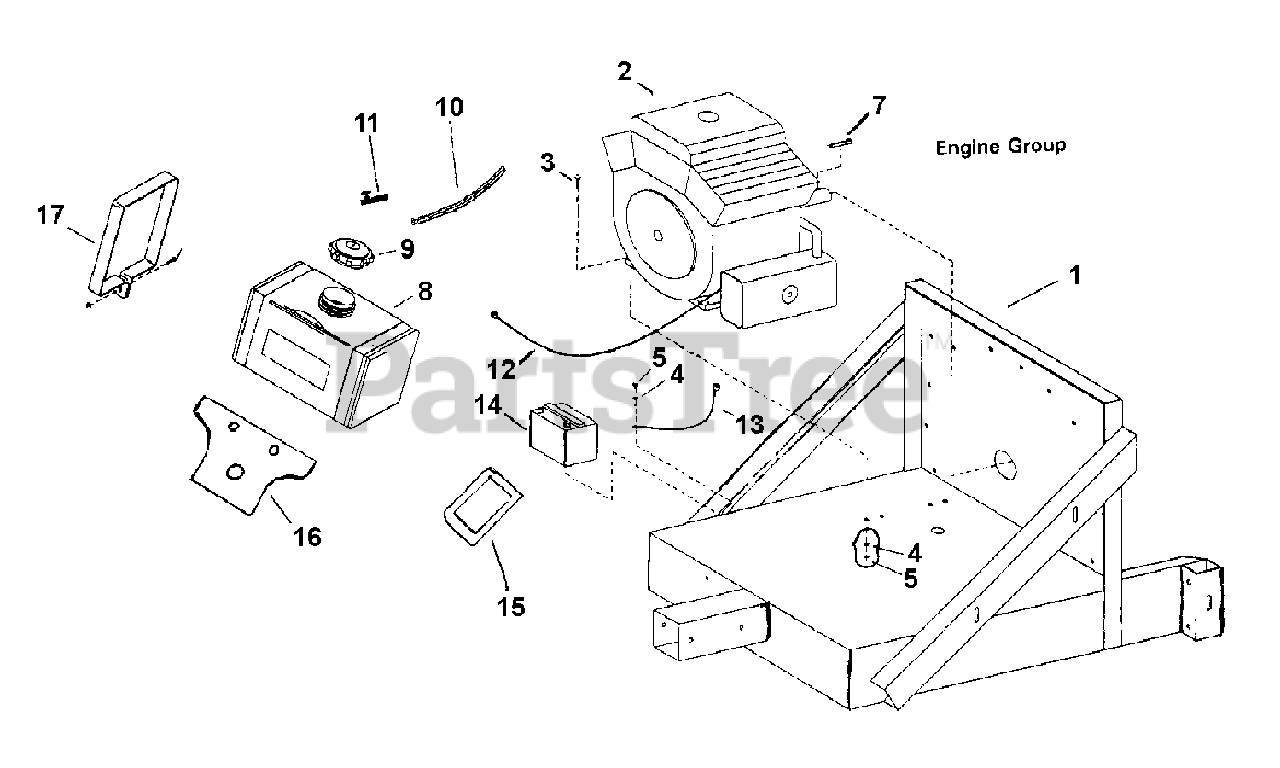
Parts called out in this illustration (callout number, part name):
1	Engine Base
2	* Engine, 35hp Briggs & Stratton Vanguard
3	Bolt, Hex 3/8 x 2 (Motor Mount Bolt)
3	Bolt, Hex 3/8 x 1-3/4 (Motor Mount Bolt)
4	Washer, Lock 3/8
5	Nut, Hex 3/8
7	5/8-18 x 2" Impeller Bolt & Key Group
8	Fuel Tank, 6 Gal.
9	Fuel Tank Cap
10	Hose, Rubber Fuel 1/4" x 10" Length
11	Inline Fuel Shutoff Valve
12	Battery Cable - 32SS (Positive)
13	Battery Cable - 16SS (Ground)
15	Battery Box
16	Gas Tank Mount
17	Fuel Tank Strap
